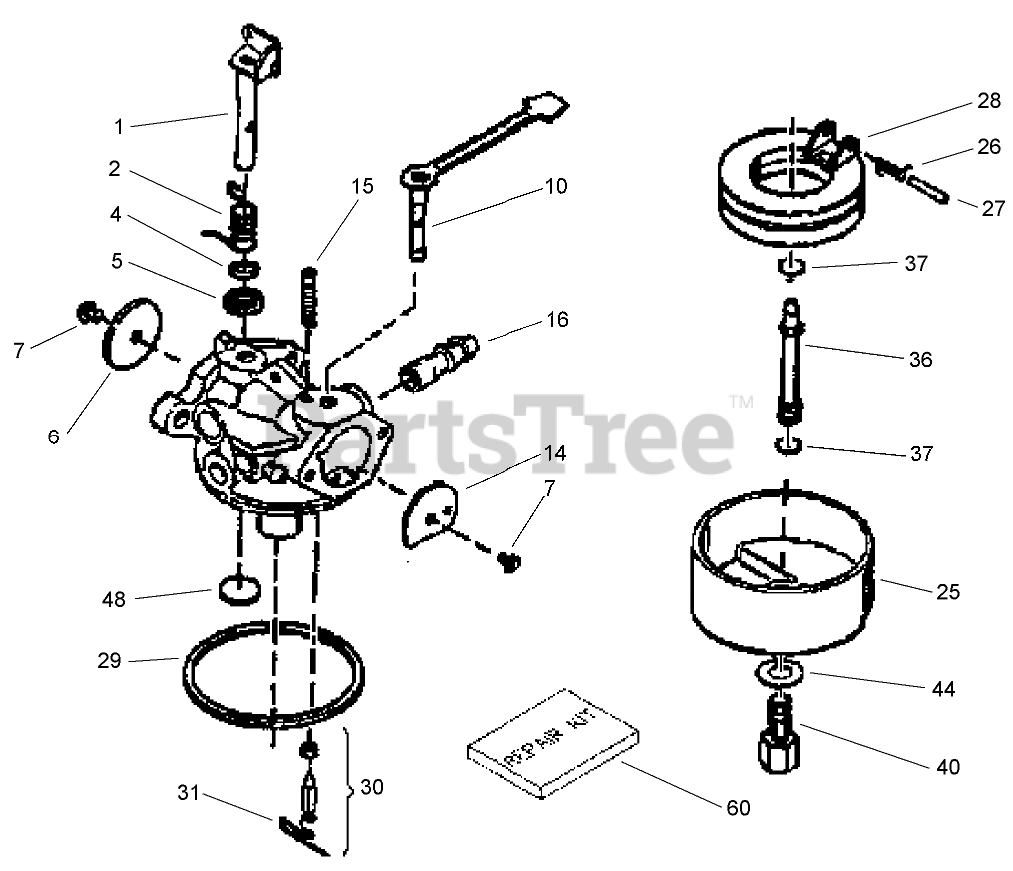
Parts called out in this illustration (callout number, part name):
1	Throttle Shaft and Lever ASM
2	Spring-Trottle, Return
4	Washer-Seal, Dust
5	Seal-Dust
6	Throttle-Shutter
7	Screw-Shutter
10	Choke Shaft and Lever ASM
14	Shutter-Choke
15	Spring-Positioning, Choke
16	Fitting-Fuel
25	Bowl-Float (no drain)
26	Spring-Float, Dampening
27	Shaft-Float
28	Float
29	O Ring-Bowl, Float
30	Inlet Needle, Seat and Clip (Incl. 31)
31	Clip-Spring
36	Tube-Nozzle, Main
37	O-Ring
40	Nut-Bowl, High Speed
44	Washer-Nut, Bowl
48	Plug-Welch, Atmospheric Vent
60	Repair Kit
